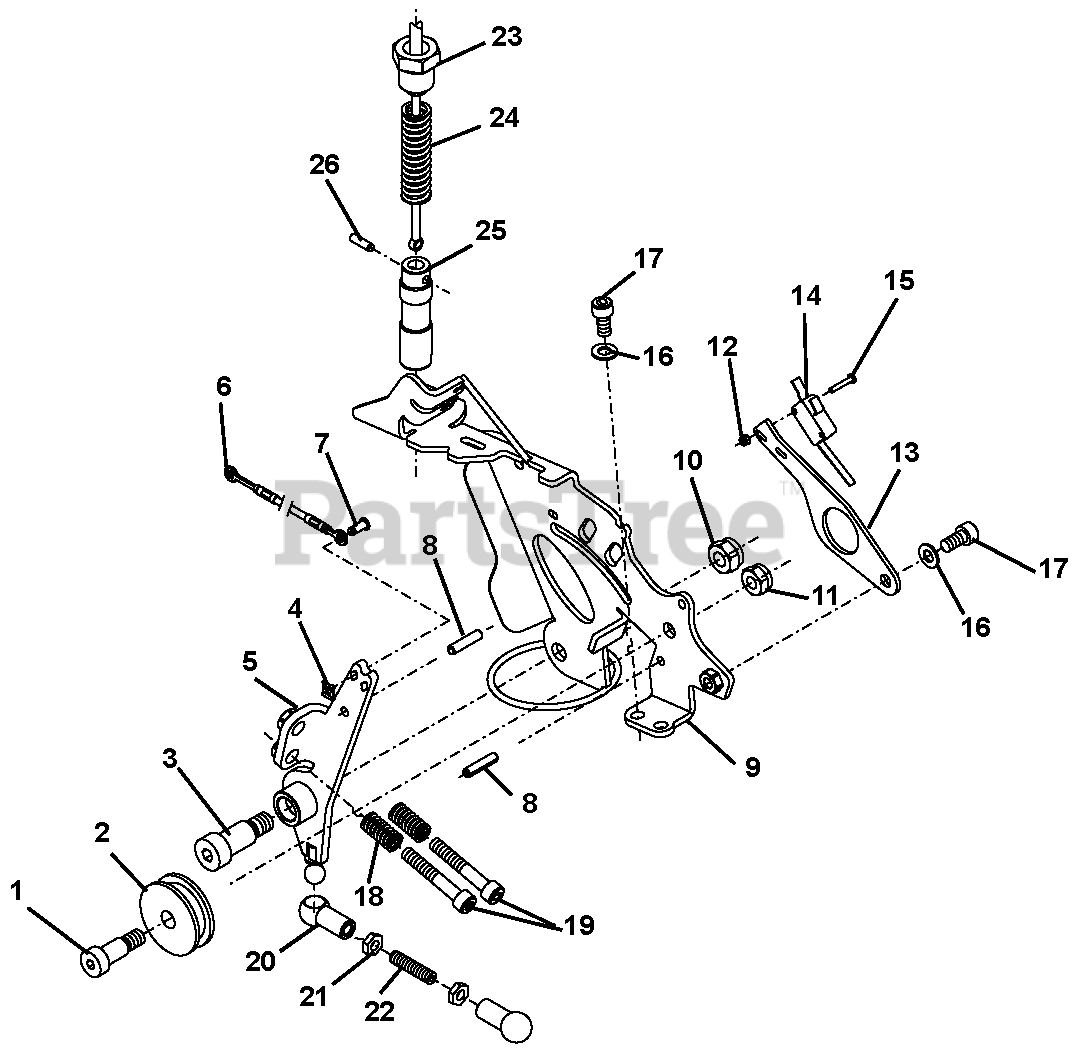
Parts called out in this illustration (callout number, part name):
4	Washer, Lock
5	Rod, Shift
6	Cable, Driving
7	Pin, Lock
8	Spring Dowel
9	Plate, Lock
10	Nut, Lock M12
11	Nut, Lock M10
12	Nut, Lock M3
13	Plate, Lock
14	Switch, Driving
15	Screw, Slit Head M3 x 18
16	Washer, M8
17	Screw, D912 M8 x 16
18	Spring, Pressure
19	Screw, M8 x 50
20	Bearing Bushing
21	Nut, Hex M8
22	Pin, Threaded M8 x 35
23	Cable, Swivelling Handlebar
24	Spring, Pressure
25	Bolt, Block
26	Pin, Straight 5-H6 x 18
